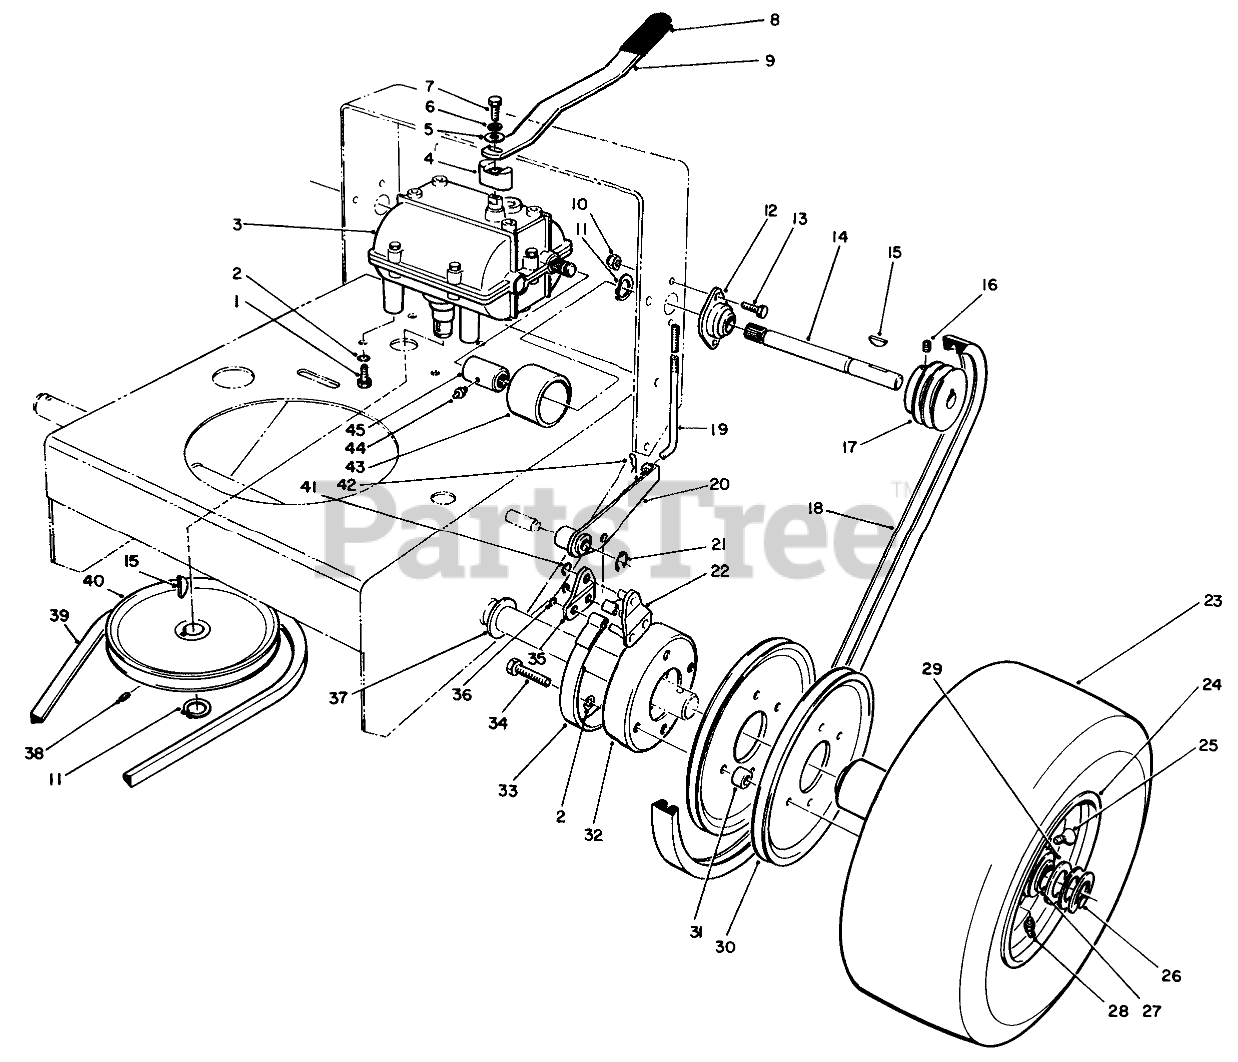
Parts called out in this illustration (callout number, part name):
1	SCREW-HH
2	WASHER-LOCK
3	TRANSMISSION
4	MOUNT-LEVER, SHIFT
5	SPACER
6	WASHER-LOCK
7	SCREW-HH
9	Lever-Shift
10	NUT-LOCK, NI
11	RING-SNAP, EXTERNAL
12	BEARING-EXTERNAL SHAFT
13	SCREW-HH
14	SHAFT-EXTENSION, RH
15	KEY-WOODRUFF
16	SCREW-SET, HS
17	Pulley-Drive
18	V-BELT
19	ROD-BRAKE
20	Brake Arm-LH
21	RING-RETAINING
22	DRIVE PIN
24	WHEEL AND HUB ASM
25	STEM-VALVE
26	RING-RETAINING
27	BEARING-BALL, FLANGED
28	FITTING-LUBE, 45 DEG
29	WASHER-THRUST
30	Pulley-Wheel
31	SPACER-PULLEY
32	Drum-Brake
33	BAND-BRAKE
34	SCREW-HH
35	Plate-Link
36	RING-RETAINING
37	WASHER-WHEEL
38	SCREW-SET
39	BELT V
40	PULLEY-DRIVEN
41	RING-RETAINING, EXTERNAL
42	PIN-COTTER
43	GUARD-COUPLER
44	FITTING-GREASE
45	COUPLER
